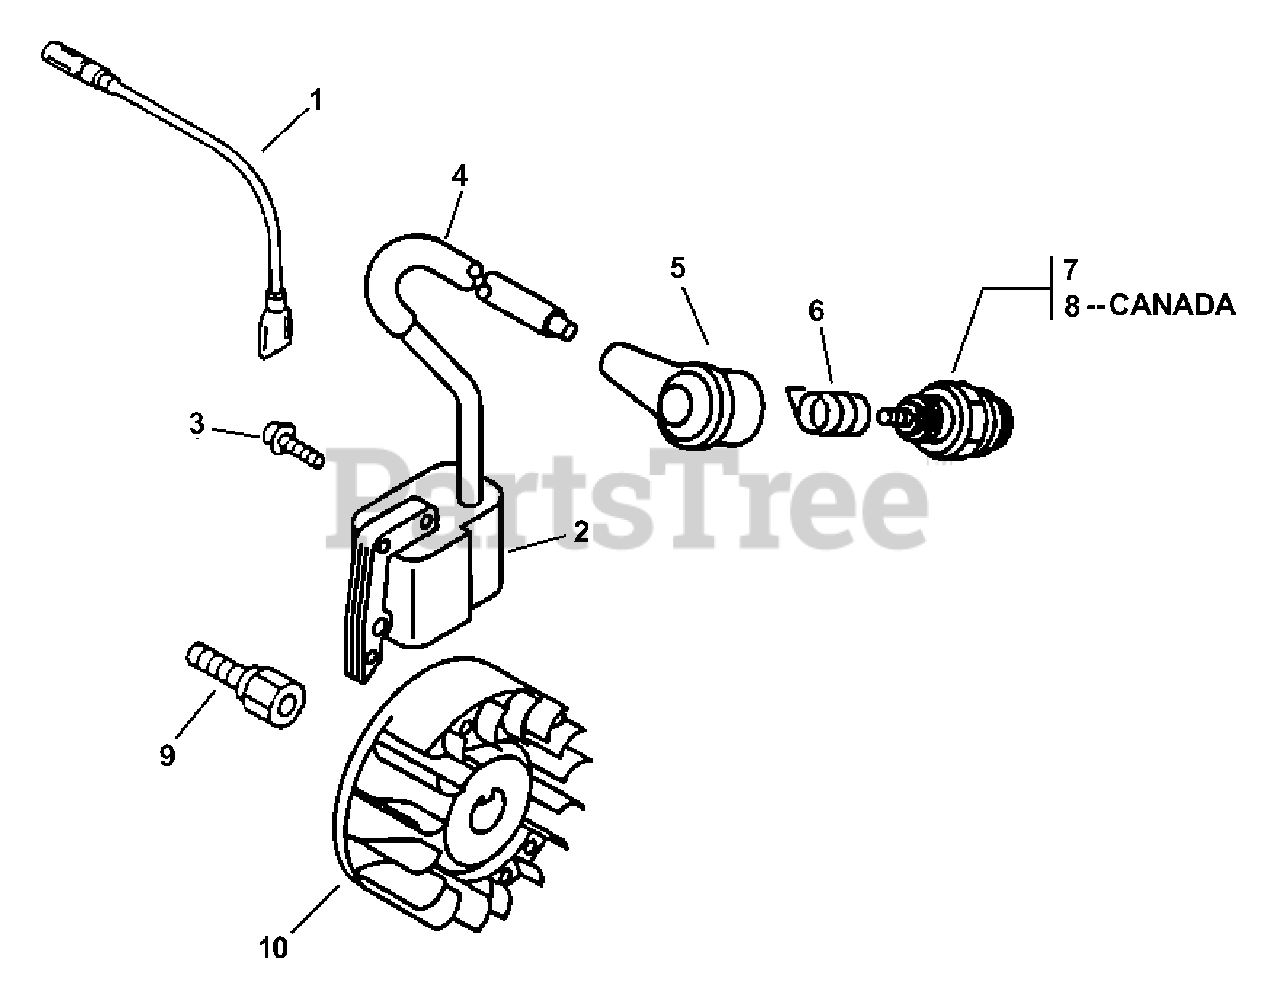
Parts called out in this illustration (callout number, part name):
1	LEAD - IGNITION
2	COIL, IGNITION
3	SCREW - 4X22
5	CAP, SPARK PLUG
6	TERMINAL, SPARK PLUG CAP
7	SPARK PLUG -- BPM-7Y
8	SPARK PLUG -- BPMR-7A
9	HUB, FAN
10	FLYWHEEL
